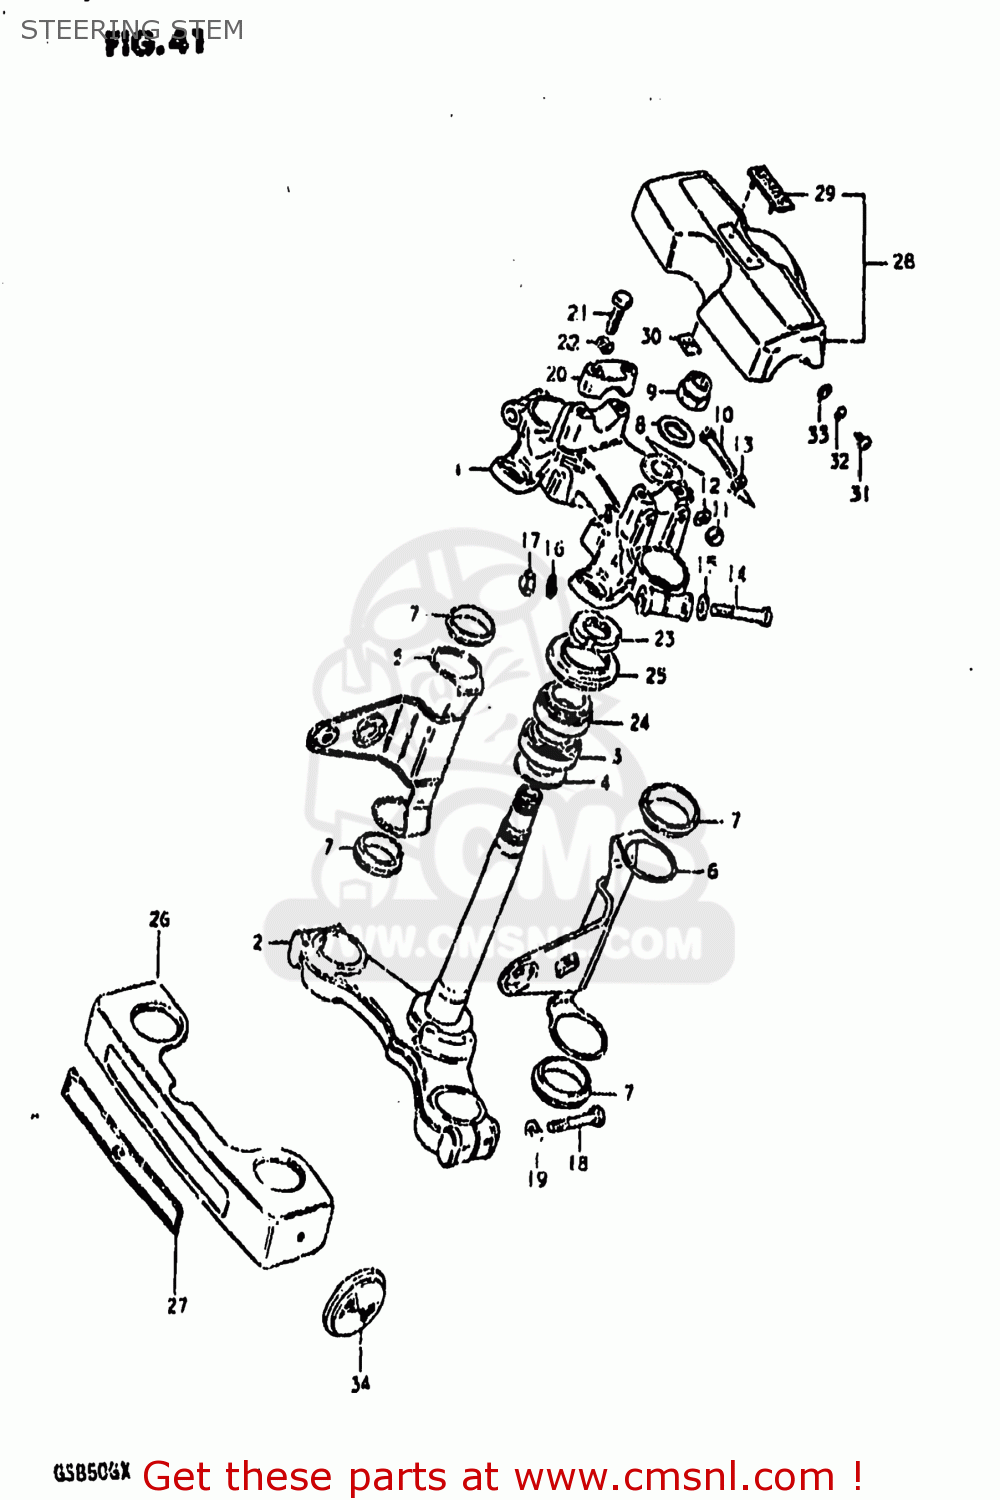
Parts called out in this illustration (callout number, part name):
1	HEAD,STEERING STEM
2	STEM,STEERING
3	BEARING
4	WASHER,THRUST
5	BRACKET,HEADLAMP,RIGHT
6	BRACKET,HEADLAMP,LEFT
7	CUSHION,HEADLAMP BRACKET
8	WASHER
9	NUT,FR FORK UPR BRACKET
10	BOLT 8X50
11	NUT
12	LOCK WASHER
13	WASHER
14	BOLT 10X55
15	WASHER
16	LOCK WASHER
17	NUT, LOWER LH
18	BOLT
19	LOCK WASHER
20	HOLDER,HANDLE(BLACK)
21	BOLT
22	LOCK WASHER
23	NUT,STEERING STEM(25X44X10)
24	TAPER,ROLLER BEARING
25	DUST SEAL,STEERING,UPPER
26	COVER,FRONT FORK
27	EMBLEM
28	PAD,HANDLEBAR
29	EMBLEM,HANDLE COVER PAD
30	NUT
31	SCREW
32	LOCK WASHER
33	WASHER
34	REFLEX REFLECTOR,RR
